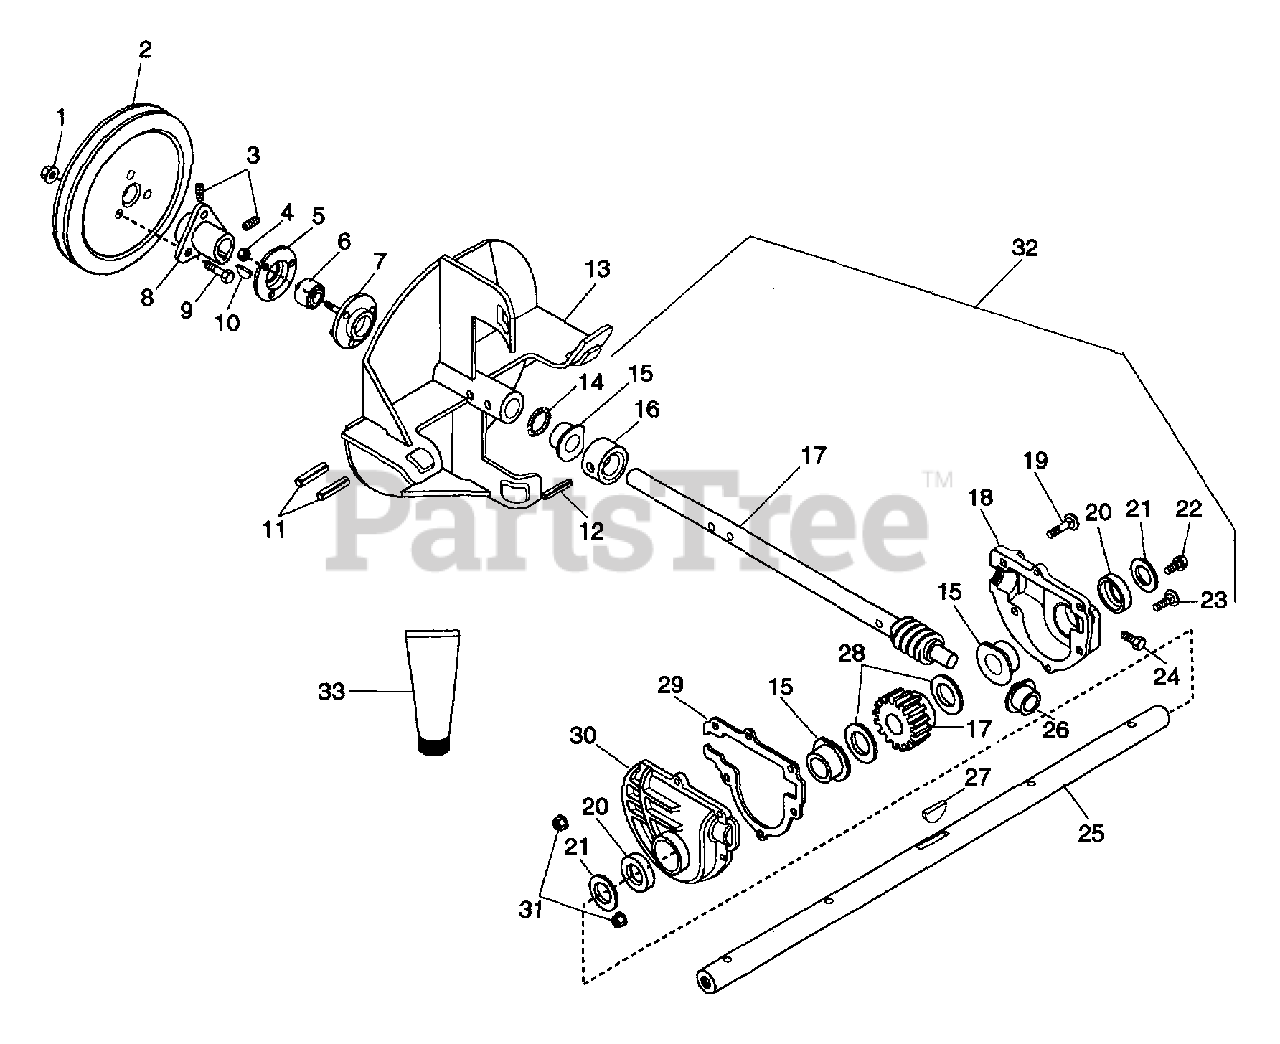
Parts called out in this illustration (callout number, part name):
1	NUT-FLG. .312-18 PL
2	PLY-V 8.50 X 1.25 3BLT
2	PLY-V 7.0 X 1.25 3 BLT
3	SCR-SET .32-18X.38 SKHCUPNL OH
4	NUT-LK-CTR .250-20 PL
5	BEARING FLANGE
6	BRG-BALL .750X1.750X.50
7	BEARING FLANGE
8	HUB
9	BLT-SERRDHD SL .31-18X.75 YZ
10	KEY-WDRF .188X.875X.375 SAE11
11	PIN-ROLL .250X1.25
12	PIN-GRV .188X1.25 TP A
13	IMPELLER - 10"
14	SEAL .750X1.00X.156
15	BSHG-FLG .750X1.000X.750X1.250
16	THRUST COLLAR
17	SHAFT AND WORM GEAR ASSEMBLY
18	L. H. GEAR CASE
19	BLT-RDHDSQNK .25-20X1.25 GR5PL
20	SEAL .750X1.000X.125
21	WSHR-FL-STL.812X1.500X.139
22	SCR-TAP 10-24X.75 HWH PL TR
23	BLT-RDHDSQNK .25-20X.88 PL
24	SCR-TAP .375-16X .50 HWH PL TR
25	SHAFT, RAKE - 20"
25	SHAFT, RAKE - 24"
26	BSHG-FLG .502X1X.750
27	KEY-WDRF .188X.625X.25 SAE 61
28	WSHR-HDND-THRST .755X1.40X.062
29	GASKET
30	R. H. GEAR CASE
31	NUT-LK-FLG .250-20 PL
32	GEAR CASE - 20" - ALUMINUM
32	GEAR CASE - 24" - ALUMINUM
33	ARIENS 16 OZ.BOTTLE OF L2 LUBE
